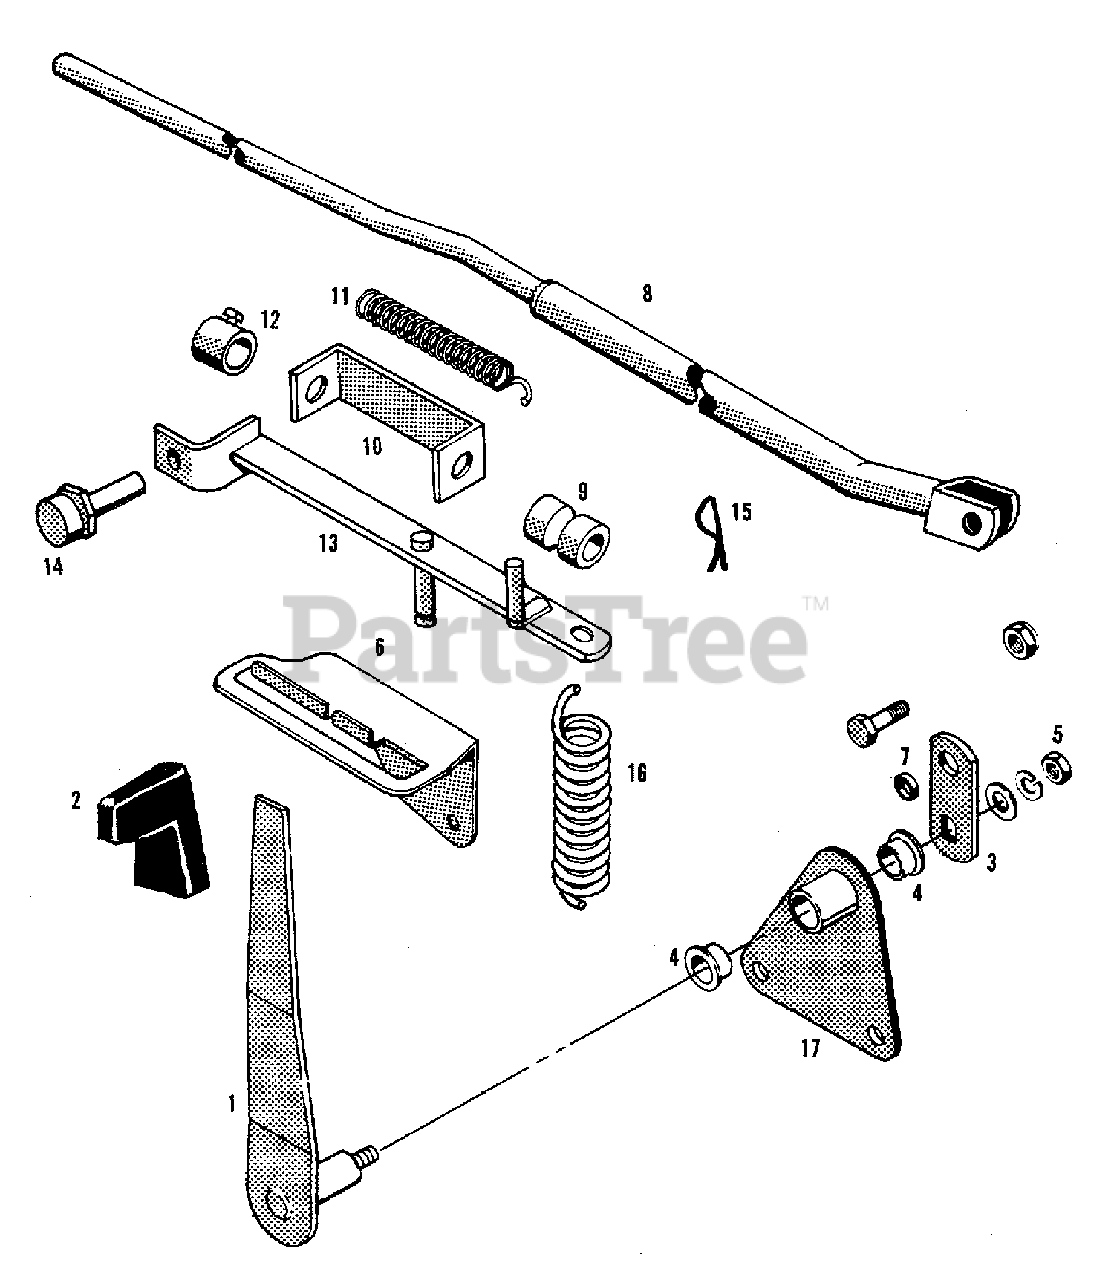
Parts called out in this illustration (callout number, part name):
1	LEVER ASSEMBLY, Control
1	SCREW, 1/4NC x 3/4, Thread Forming
4	BUSHING, Flanged
4	WASHER, 3/8
4	LOCKWASHER
5	NUT, 3/8NC
6	CAPSCREW, 1/4NC x 5/8
6	LOCKWASHER, 1/4
6	NUT, Cage, 1/4NC
7	CAPSCREW, 3/8NC x 1
7	NUT, 3/8NC, Lock
8	ROD ASSEMBLY
9	BRAKE, Detent
9	SETSCREW, 1/4NC x 3/8, GR8
10	GUIDE ASSEMBLY, Rod
10	WASHER, .281 x 5/8, 18GA
11	NUT, 3/8NC, Lock
12	COLLAR SET
12	SETSCREW, 1/4NC x 3/8, GR8
13	LEVER ASSEMBLY, Brake
14	PAD ASSEMBLY, Brake
14	NUT, 5/16NC
15	PIN, 3/32 x 3/4, Cotter
16	WASHER, 5/16
17	BRACKET ASSEMBLY, Support
17	SETSCREW, 5/16NC x 1/2
17	CAPSCREW, 5/16NC x 3/4
17	LOCKWASHER, 5/16
17	WASHER, 5/16
17	NUT, 5/16NC
